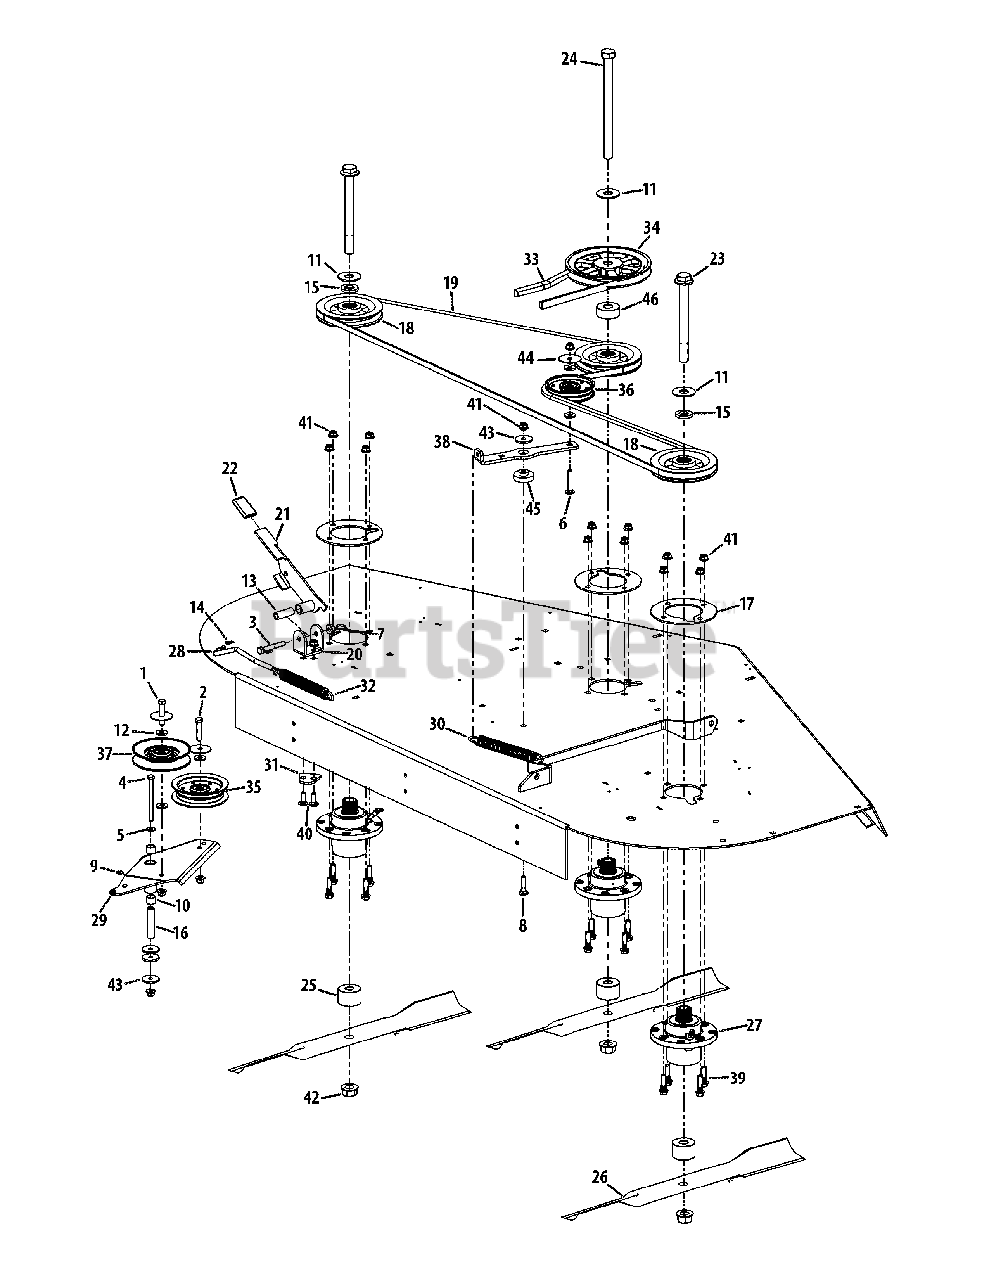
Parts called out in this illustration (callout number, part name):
1	Hex Screw, 3/8-16 x 2.00
2	Hex Screw, 3/8-16 x 1.75
3	Hex Screw, 3/8-16 x 2.50
4	Hex Screw, 3/8-16 x 4.00
5	Washer, .406 x .813 x .063
6	Carriage Bolt, 3/8-16 x 2.00
7	Flange Counter Locl Nut, 3/8-16
8	Carriage Bolt. 3/8-16 x 1.50
9	Grease Fitting, 1/4-28
10	Sleeve Bearing, .628 x.753 x.625
11	Washer, .781 x 2.00 x .105
12	Washer, .406 x 1.00 x .105
13	Spacer, .390 x .630 x 1.75
14	Hair Pin, 1/8 x 1.125 x .072
15	Spacer, .812 x 1.47 x .218
16	Spacer, .390 x .635 x 2.75
17	Spindle Support Plate
19	V-Belt
20	Idler Tension Bracket
21	Tension Handle Weldment
22	Idler Tension Handle Grip
23	Hex Screw, 3/4-16 x 7.50
24	Hex Screw, 3/4-16 x 9.50
25	Spacer, .760 x 2.00 x 1.28
26	Blade, 25"
27	Spindle Assembly
28	Tensioner Spring Rod
29	Idler Double Weldment
30	Extension Spring, .94 x 7.57 x .14
31	Idler Spring Bracket Adapter Plate
32	Extension Spring, .94 x 7.74 x .14
33	V-Belt
35	Idler Pulley
36	Idler Pulley
37	Idler Pulley
38	Deck Idler Arm
39	Flange Bolt, 3/8-16 x 1.5
40	Carriage Bolt, 3/8-16 x 1.00
41	Flange Lock Nut, 3/8-16
42	Flange Lock Nut, 3/4-16
43	Flat Washer, .390 x 1.500 x .134
44	Flat Washer, .406 x 1.92 x .060
45	Shoulder Spacer, .854 x .280
46	Spacer, .760 x 2.000 x .790
